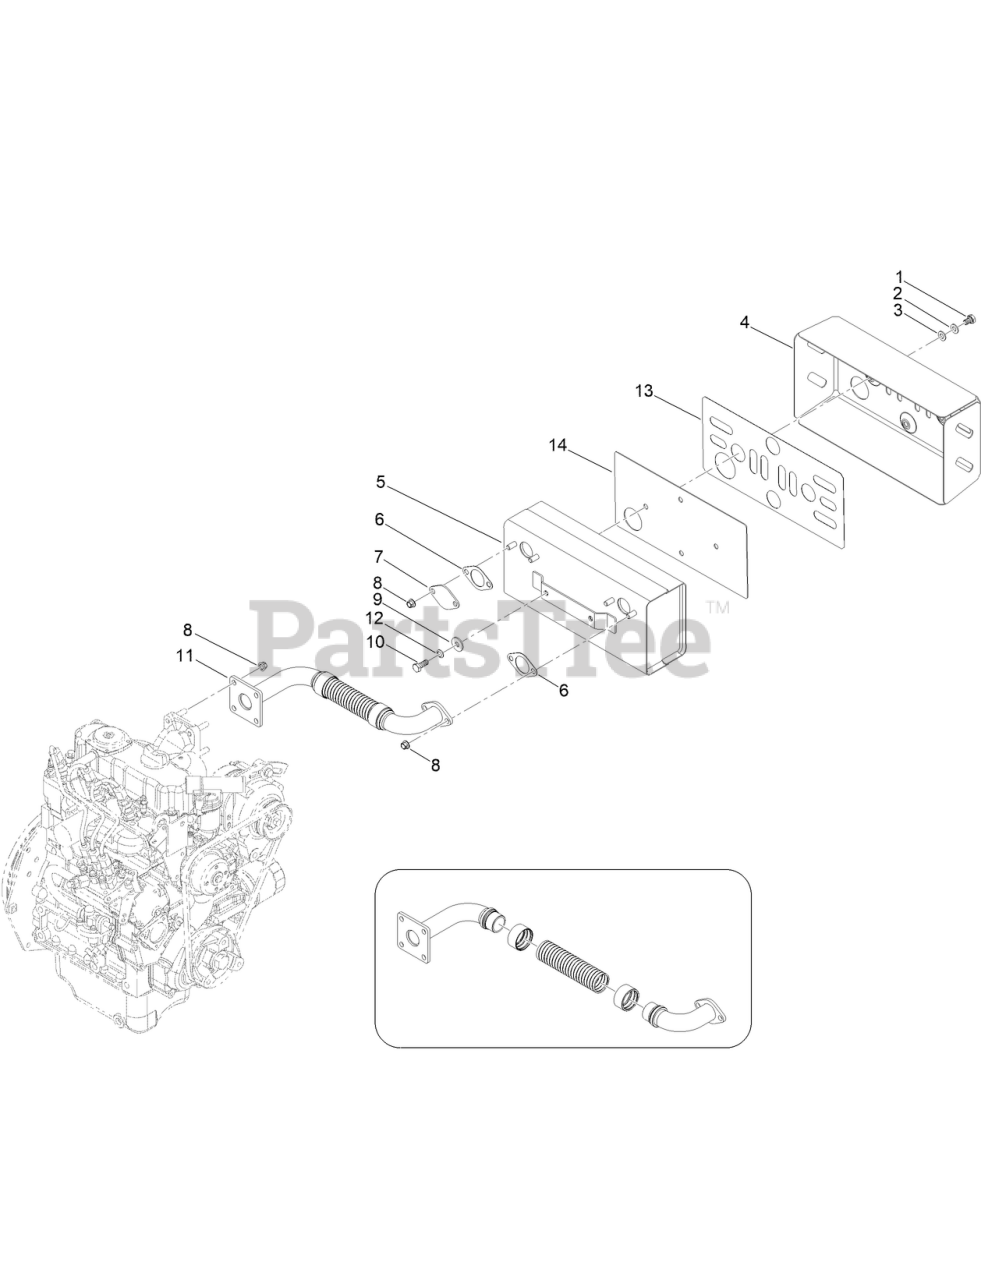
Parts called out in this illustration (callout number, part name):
2	WASHER
3	WASHER
4	COVER, MUFFLER
5	MUFFLER
6	GASKET, MUFFLER
7	FLANGE, MUFFLER
9	WASHER
11	MANIFOLD, EXHAUST
12	WASHER
13	TAPE, MUFFLER
14	PLATE, SPACER-MUFFLER
